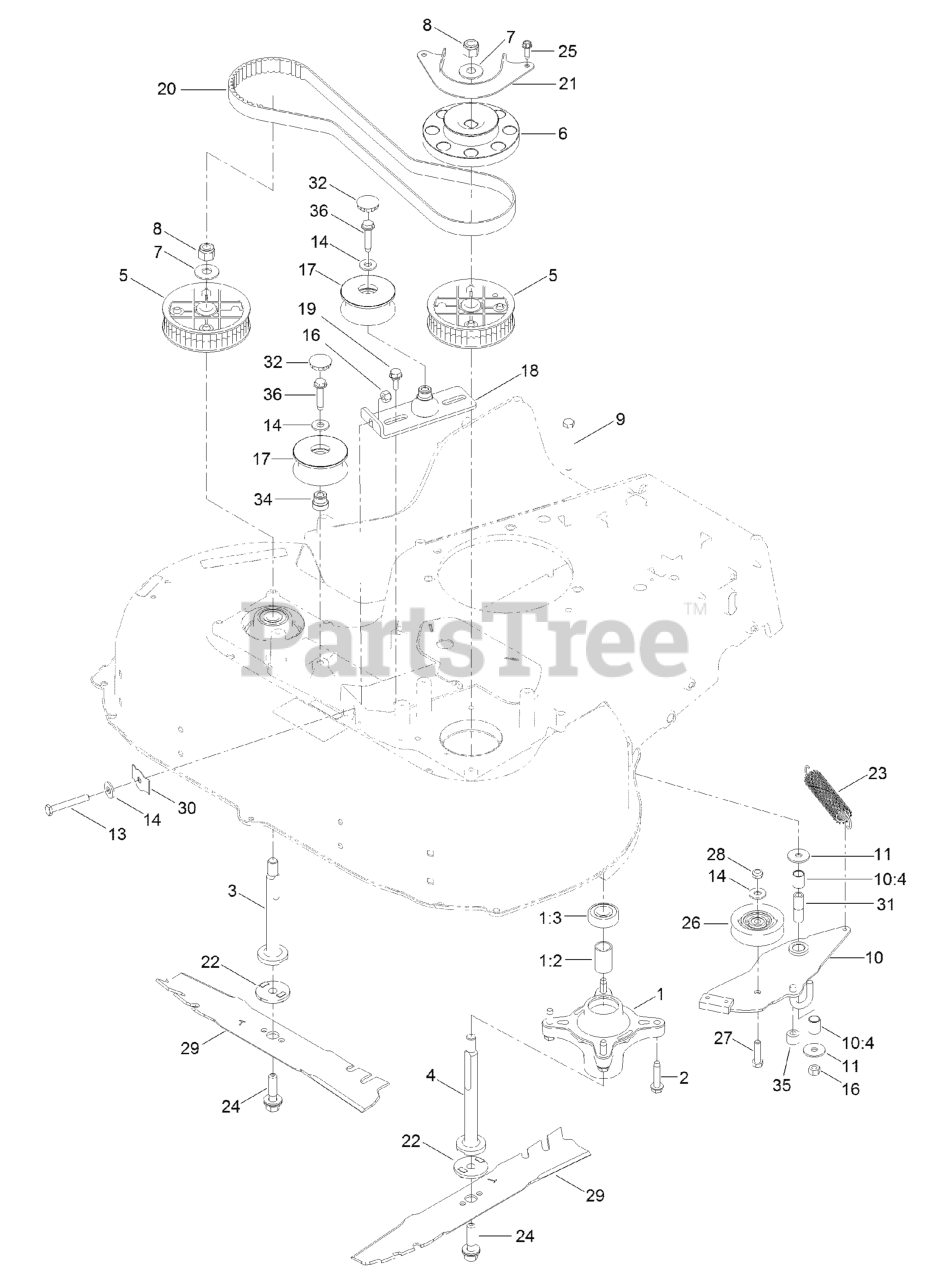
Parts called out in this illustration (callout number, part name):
1	SPINDLE ASM
1:3	BEARING-BALL
3	SHAFT-SPINDLE
4	SHAFT-SPINDLE
5	SPROCKET
6	PULLEY-BRAKE, SPINDLE
7	WASHER-SPRING
8	NUT-HEX
9	SCREW-HH
10	BRAKE ARM ASM
10:4	BUSHING-SLEEVE
11	WASHER-PIVOT
13	BOLT-TAP, HH
14	WASHER-FLAT
16	NUT-LOCK, NI
17	PULLEYS AND IDLER KIT
18	BRACKET-IDLER
19	SCREW-SHOULDER,HWH
20	BELT-SYNCHRONOUS
21	GUIDE-BELT, SPINDLE
22	ADAPTER-BLADE
23	SPRING-EXTENSION, BRAKE
24	BOLT-BLADE
25	SCREW-HWHTF
26	PULLEY-IDLER
27	SCREW-HH
28	NUT-LOCK, NI
29	BLADE-ROTARY
30	SPRING-FLAT
31	SPACER-BRAKE
32	PLUG-BUTTON
34	ADAPTER-BORE
35	HOSE-COOLANT
